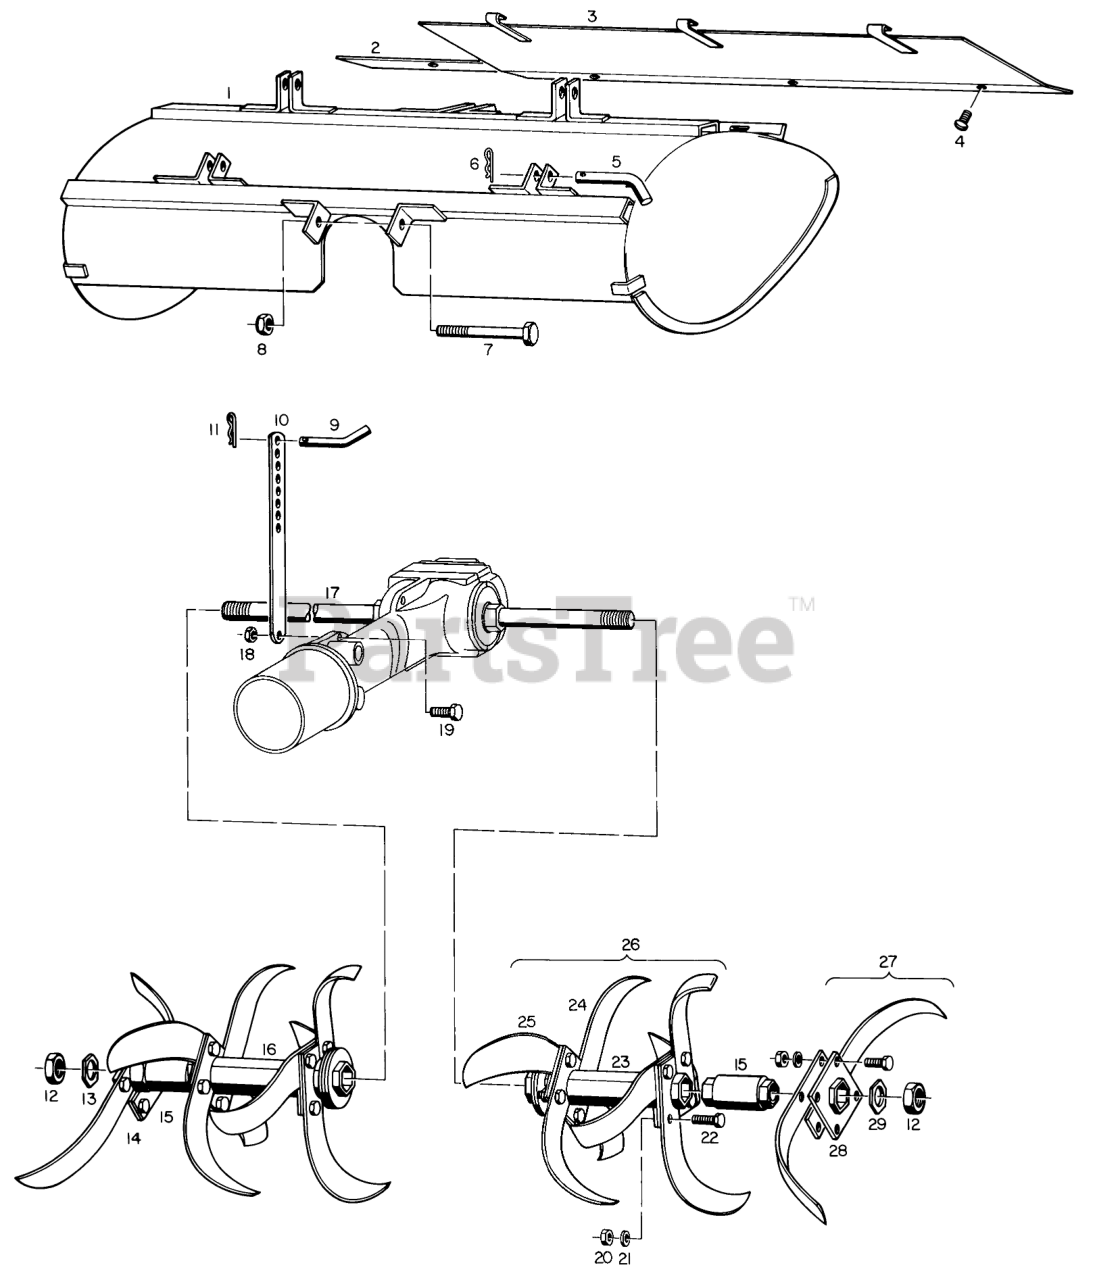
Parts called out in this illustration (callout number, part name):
1	Hood Assembly
2	Ballast Plate
3	Rear Drag Plate
4	Screw
5	"L" Clevis Pin
6	Hairpin Cotter
9	"L" Clevis Pin
10	Adjusting Lever
11	Hairpin Cotter
13	Lockwasher
14	R. H. Outside Tine Assembly, Same as 27, except with two #24 Left Hand Tines
15	Spacing Hub
16	R. H. Inside Tine Assembly (Consists of Parts 20-25)
17	Tine Shaft
21	Washer
23	Tine Carrier Plate Assembly
24	Left Hand Tine
25	Righ Hand Tine
26	L.H. Inside Tine Assembly (Consists of Parts 20-25)
27	L.H. Outside Tine Assembly (Consists of 20, 21, 22, 28 and 29)
28	Carrier Plate Assembly
29	Lockwasher
30	Decal
